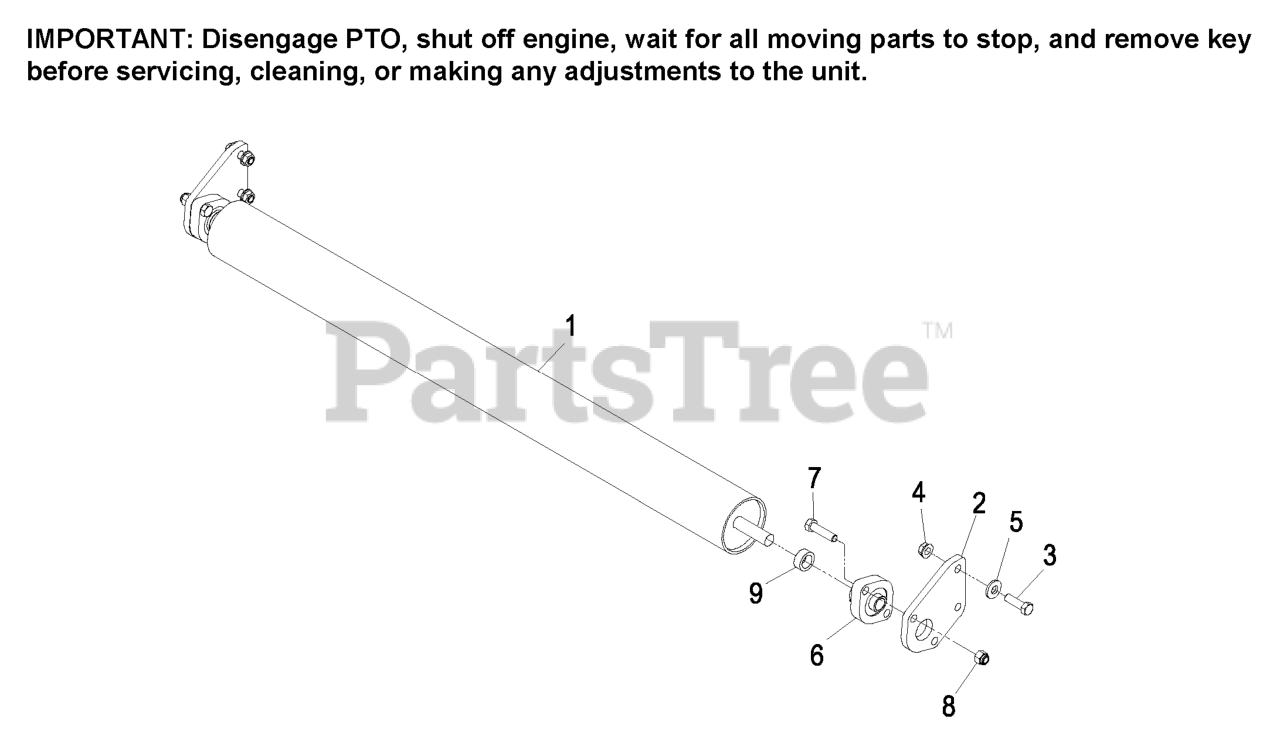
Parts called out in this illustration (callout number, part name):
2	BRACKET,STRIPER
3	SCREW-HH
4	NUT-HHF, WHIZ
5	WASHER-BELLEVILLE
6	BEARING, FLCT 5/8 1010KRR
7	SCREW-HH
8	NUT-LOCK, NI
9	SPACER,BEARING
